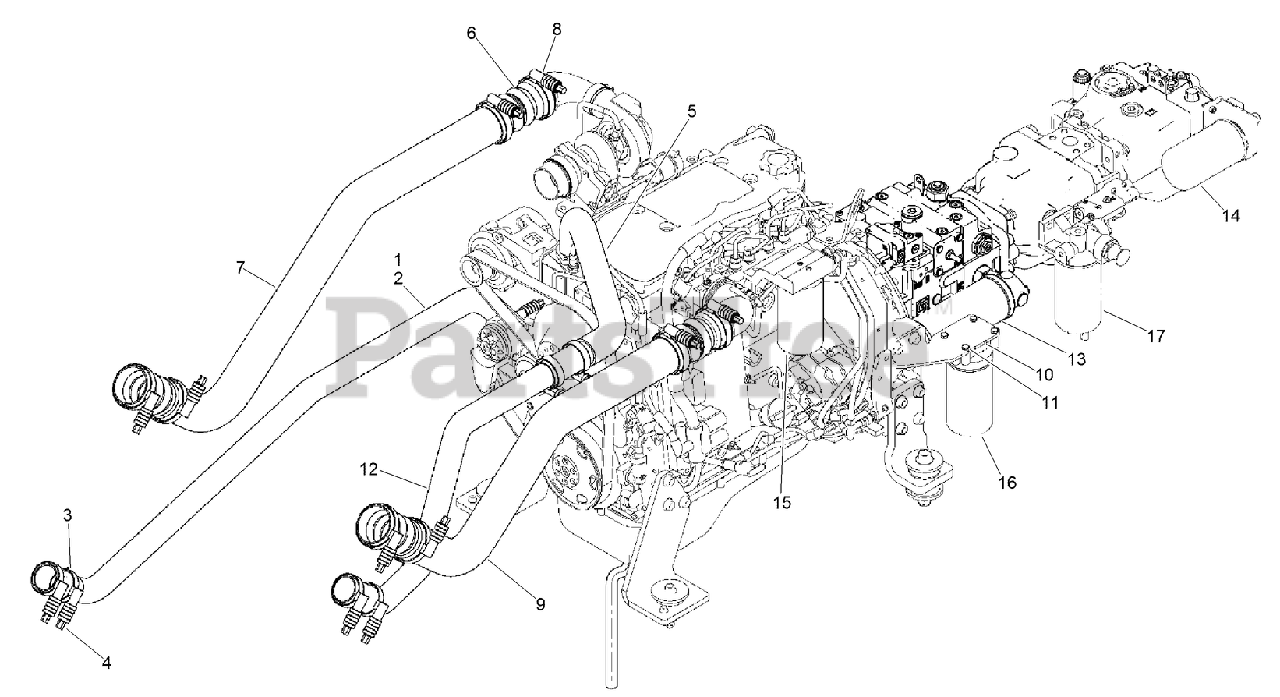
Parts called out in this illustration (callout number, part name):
1	ELBOW - 45 Deg Rubber, Purosil 45L20
2	HOSE-Radiator Out, Moulder
3	HOSE-CONNECTING
4	CLAMP-TORQUE, CONSTANT
5	HOSE - Radiator in, Molded
6	CONNECTOR-HOSE
7	TUBE - In, Charge Air
8	CLAMP-TORQUE, CONSTANT
9	TUBE - Out, Charge Air
10	PLATE - Filter Mount
11	BOLT-Hex, 5/16 NC x 1-1/2 inch
12	TUBE - Radiator
13	FILTER-CHARGE
14	FILTER-CHARGE
15	FILTER - Inline Fuel
16	FILTER - Engine Oil
17	FILTER - Fuel, Water Separator
